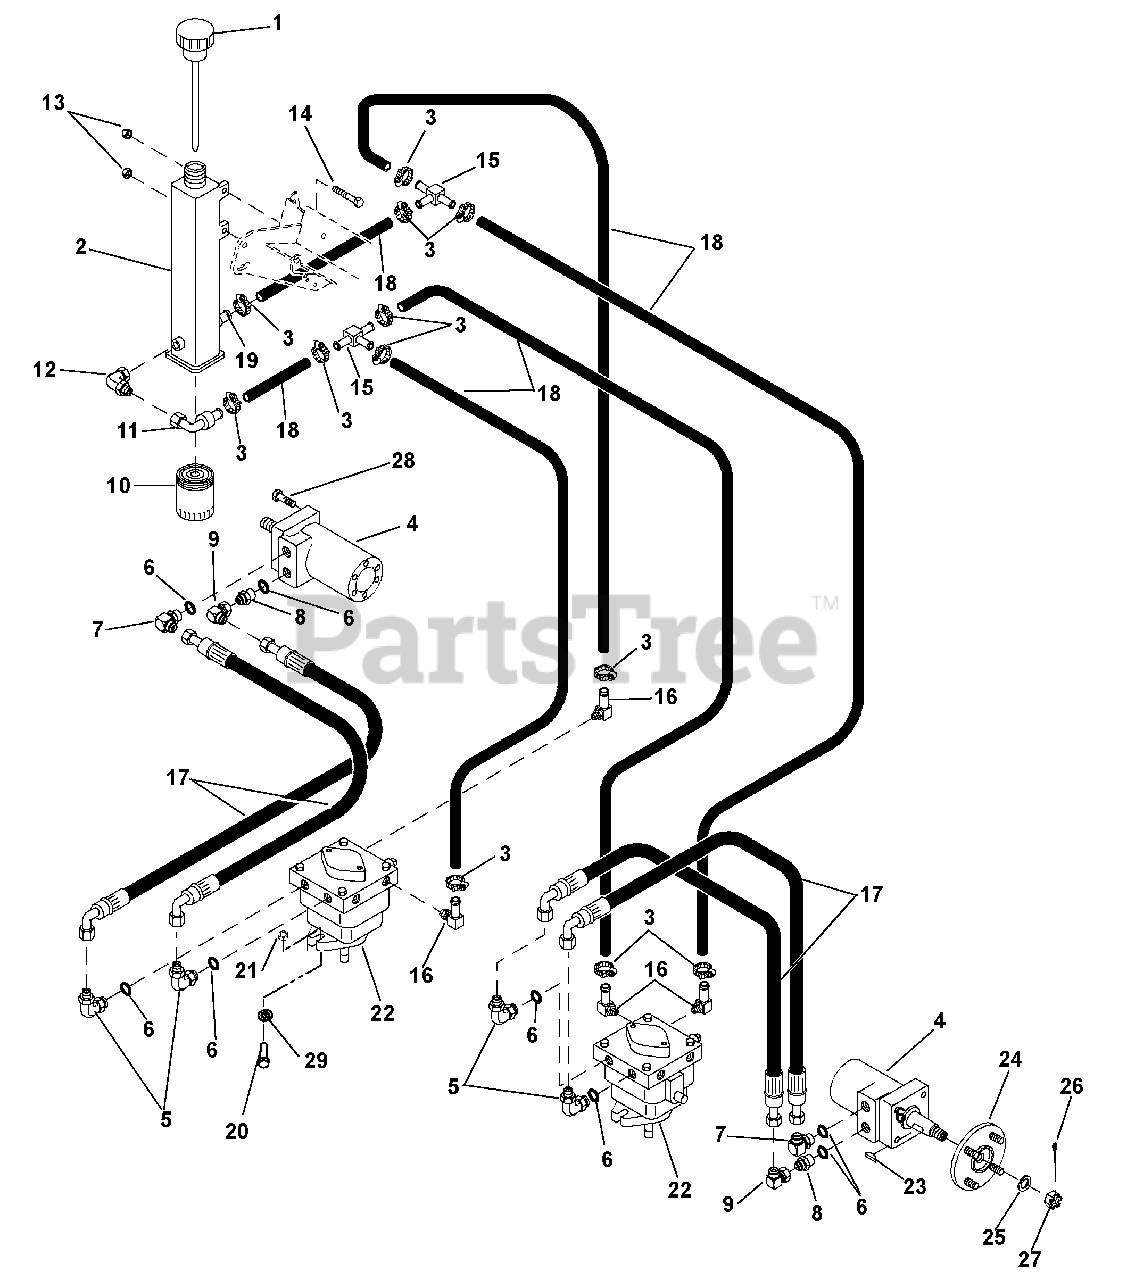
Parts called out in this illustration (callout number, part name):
1	Cap, Filler, Oil
2	Hydraulic Reservoir
3	Hose Clamp
4	Motor, Hydraulic Wheel
5	Fitting, 90 ADP JIC-Orbit 6801-08-08
6	O-Ring, Included With Fitting
7	Fitting, 7/8ORB x 3/4JIC x 90
8	Fitting, ADP 3/4-16 MJIC x 7/8-14MOR
9	Adapter, 3/4 FESW x 3/4MJIC x 90
10	Filter, Oil
11	Elbow Fitting
12	Fitting, 90 9/16 MOR x 9/16 MJIC
13	Nut, Locking, Nylon M10-1.5
14	Screw, Hex, Flat M10 x 1.5 x 25
15	Fitting, TUN, .38 Hose
16	Fitting 90 9/16 MOR x 3/8" Hose
17	Hose Assembly
18	Hose, .38 SAE30R7 Fuel and Oil
19	Adapter, Straight Fitting
20	Carriage Bolt, Pump Mounting, M10
21	Nut, Locking, Nylon M10-1.5
22	Pump, Hydraulic RH
23	Key, Woodruff .19 x .75 HRD #9
24	Assembly, Rear Wheel Hub
25	Bushing, Machine .750 x 1.25 x .048
26	Pin, Center .125 x 2.00
27	Nut-Hex-Slotted .75-20
28	Bolt, Hex .38-16 x 1.00 Grade 5
29	Washer, Flat, Steel .38 x .875 x .083
